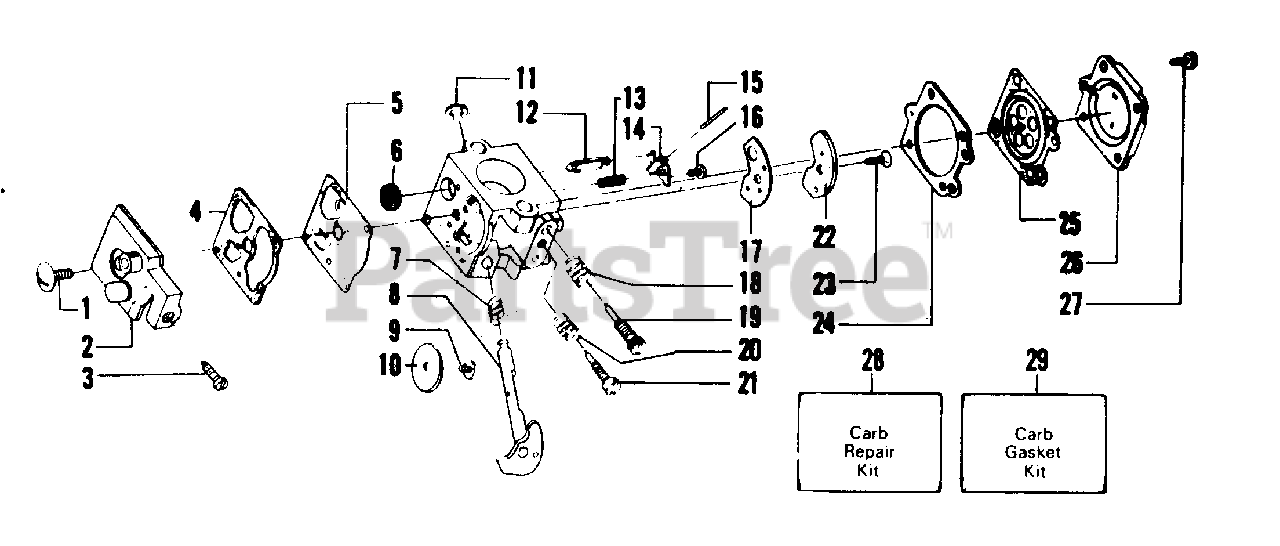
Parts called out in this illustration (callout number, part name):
1	Screw - Pump Cover
2	Pump Cover
3	Screw - Idle Adjustment
4	Gasket - Pump
5	Diaphragm - Pump
6	Screen - Inlet
7	Spring - Throttle Return
8	Shaft Assembly - Throttle
9	Screw - Throttle Valve
10	Valve - Throttle
11	Clip - Throttle Shaft
12	Valve - Inlet Needle
13	Spring - Metering Lever
14	Lever - Metering
15	Pin - Metering Lever
16	Screw - Metering Lever Pin
17	Gasket - Circuit Plate
18	Spring - Hi Speed Needle
19	Needle - Hi Speed
20	Spring - Idle Needle
21	Needle - Idle
22	Plate - Circuit
23	Screw - Circuit Plate
24	Gasket - Metering Diaphragm
25	Diaphragm Assembly - Metering
26	Cover - Metering Diaphragm
27	Screw Assembly - Metering Cover and Throttle Shaft Clip
28	Kit - Carb. Kwik Repair
29	Kit - Carb. Gasket/Diaphragm
